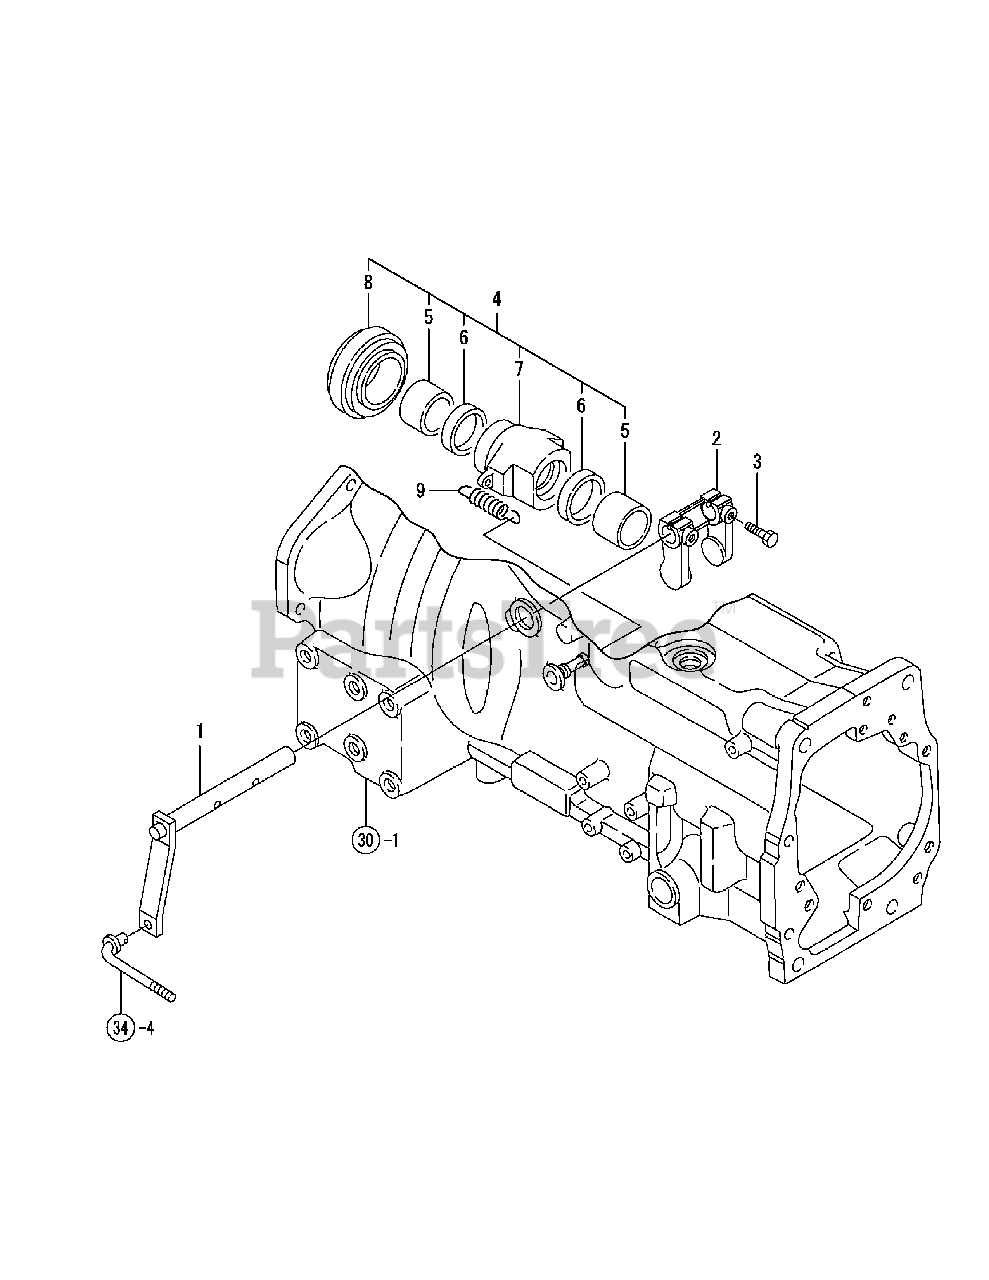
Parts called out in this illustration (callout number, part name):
1	SHAFT,CLUTCH RELEASE
2	YOKE, CLUTCH SHIFT
4	SLEEVE ASSY, BEARING
7	SLEEVE, BEARING
8	BEARING, CLUTCH
